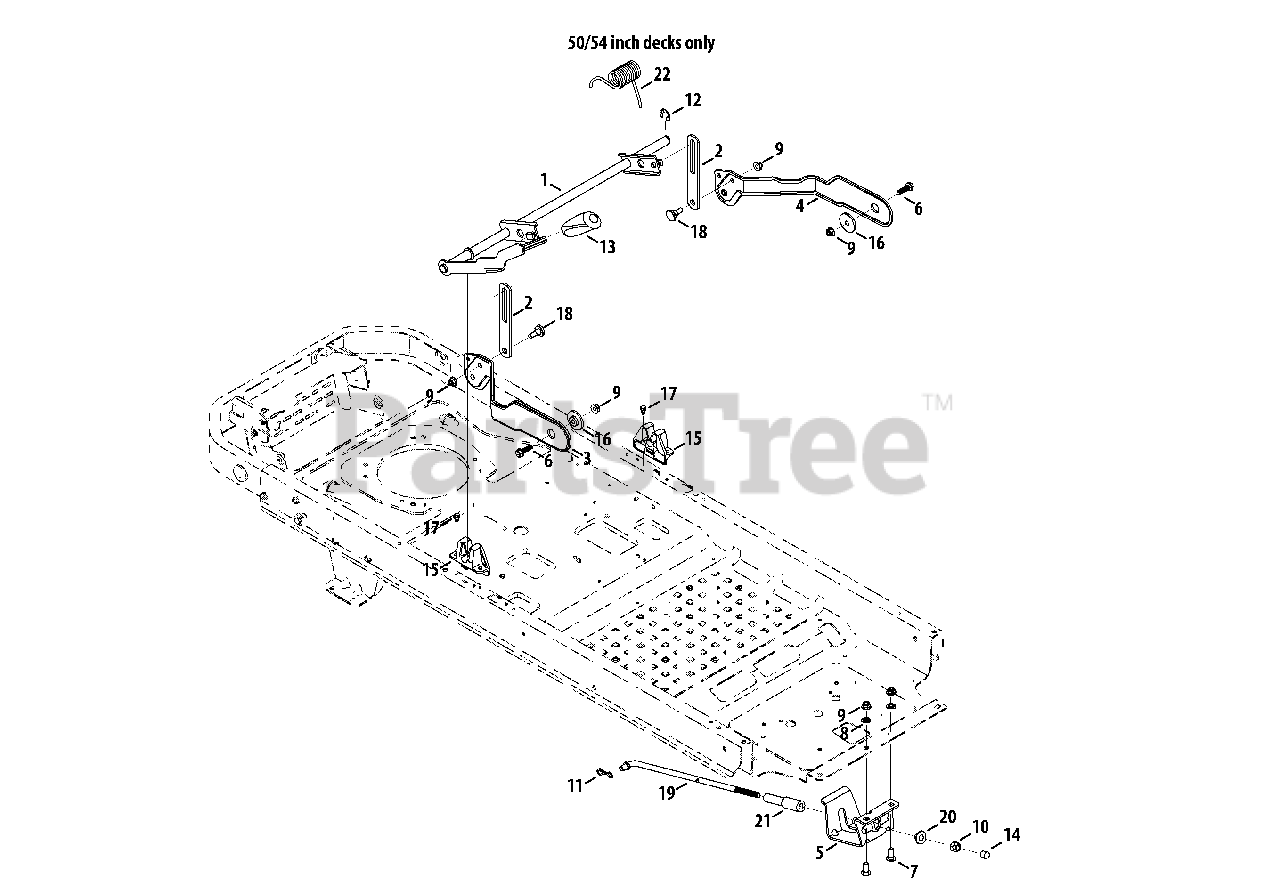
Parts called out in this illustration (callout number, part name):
1	Deck Lift Shift Assembly
2	Lift Link Plate
3	Deck Lift Plate, RH
4	Deck Lift Plate, LH
5	Rod Support Mounting Bracket
6	Hex Washer Screw, 3/8-16 x 1.250
7	Carriage Bolt, 3/8-16 x 1.00
8	Push Nut, 3/8
9	Flange Lock Nut, 3/8-16
10	Flange Lock Nut, 1/2-13
11	Bow-Tie Cotter Pin
12	E-Type Ring, .750
13	Grip, .50 ID
15	Deck Lift Bracket
16	Shoulder Spacer, .884 x .190
17	Shoulder Screw, .500 x 1/4-20
18	Shoulder Screw, .500 Dia. x .434
19	Deck Lift Rod
20	Deck Lift pivot Cup
21	Nylon Sleeve, .55 ID x 4.50 LG
22	Torsion Spring, 1.323 ID x 2.83 LG
